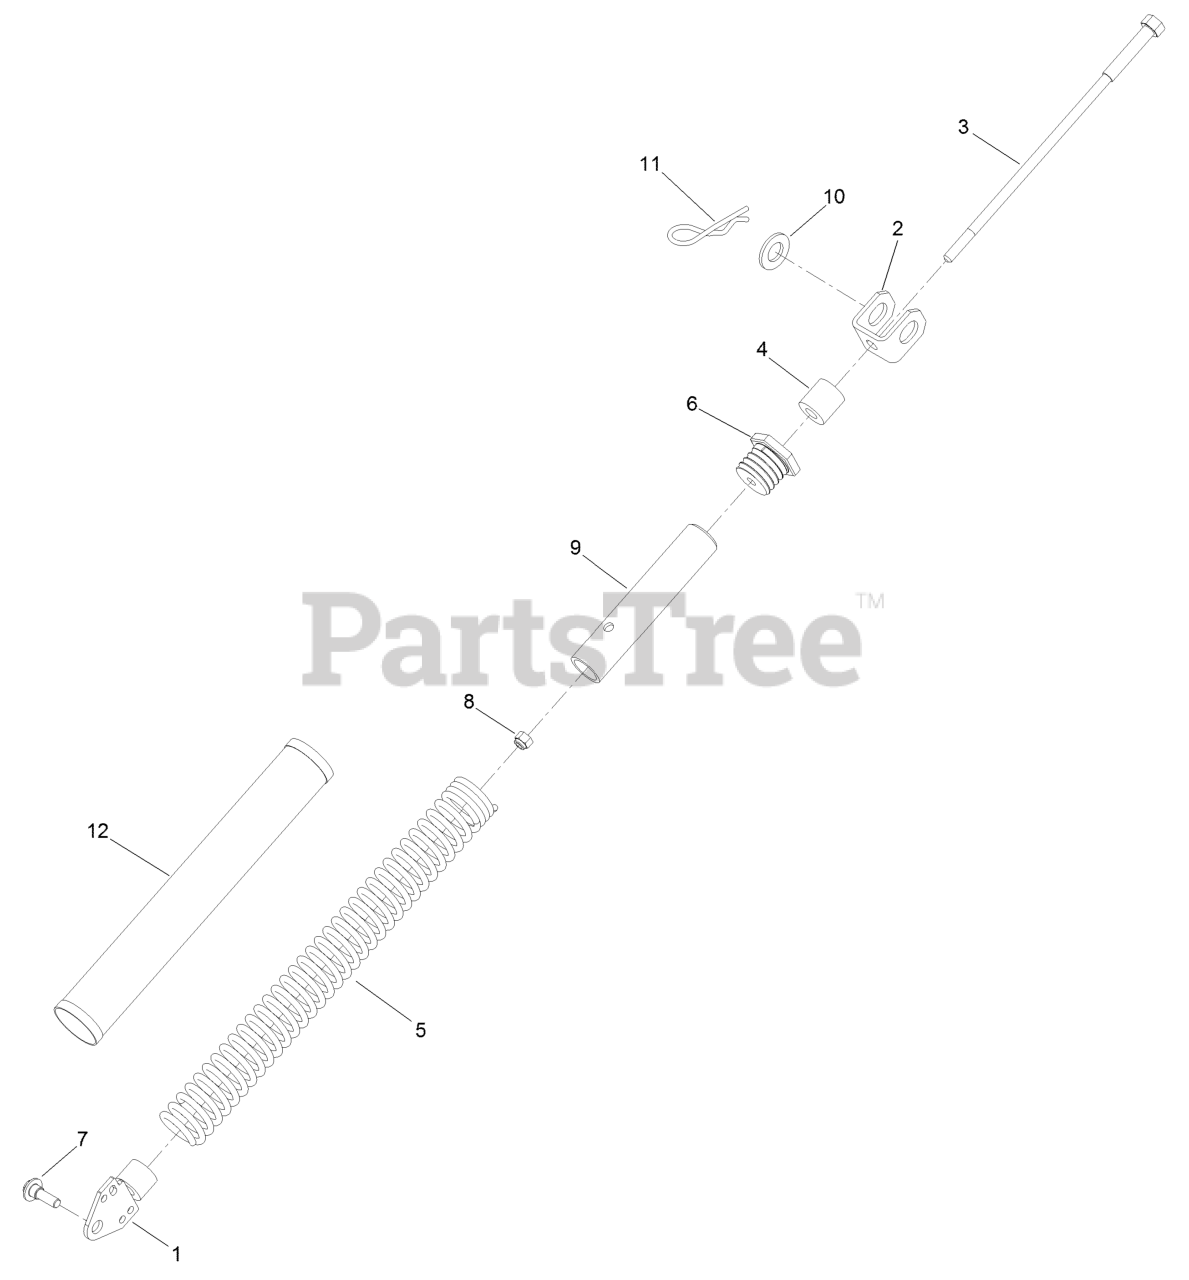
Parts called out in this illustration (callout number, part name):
1	TENSIONER-SPRING
2	MOUNT-LIFT ASSIST, DECK
3	SHAFT-ADJUSTMENT, SPRING
4	SPACER (PLATED)
5	SPRING-EXTENSION
6	PLUG-ADJUSTER, SPRING
7	SCREW-SHOULDER, HWH
8	NUT-LOCK, NI
9	SPRING-TUBE
10	WASHER-FLAT
11	PIN-CUT HEIGHT
12	COVER-SPRING, DECK
